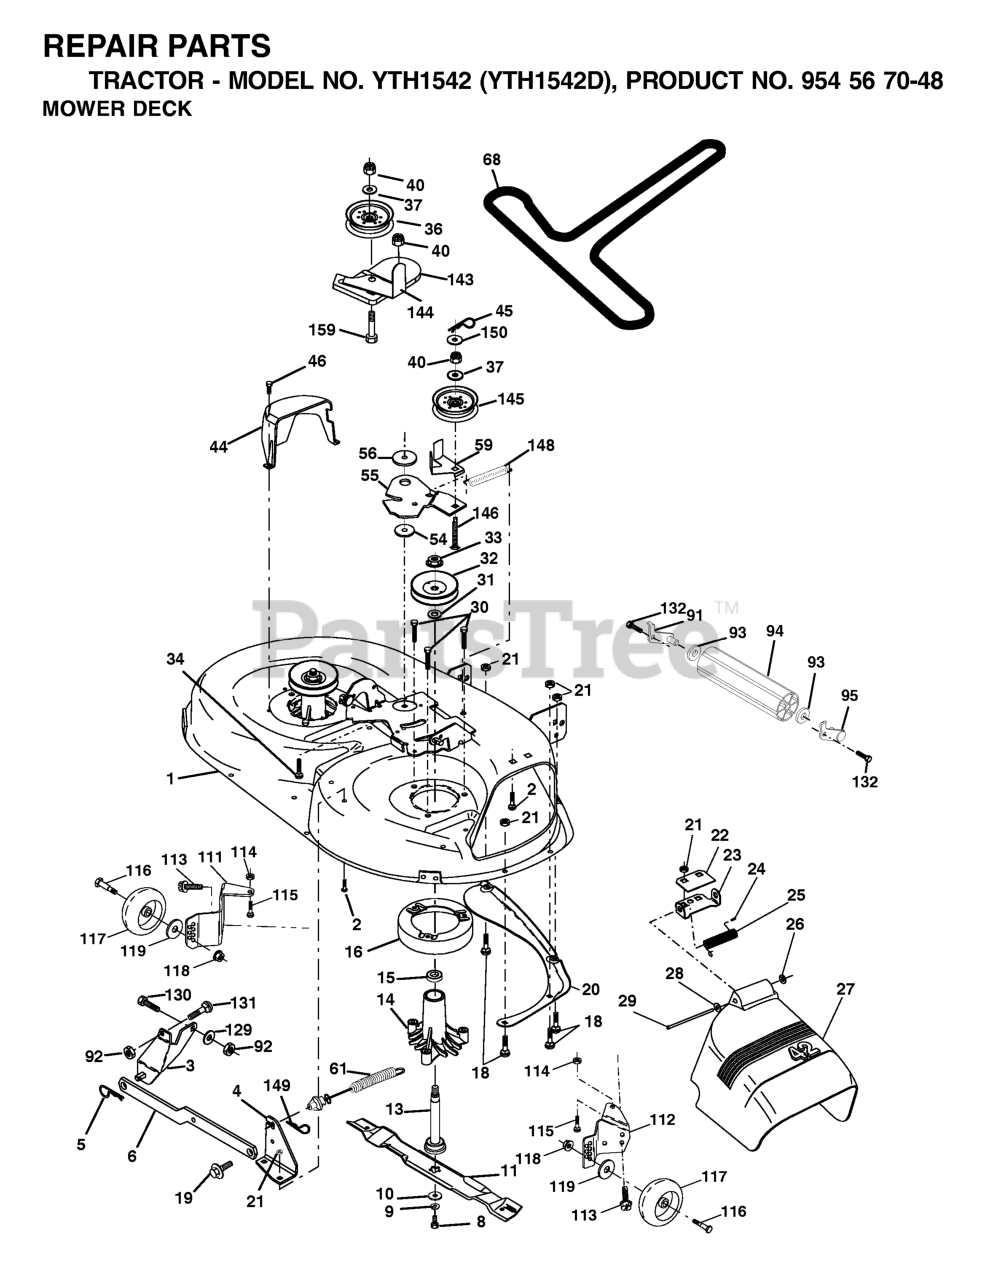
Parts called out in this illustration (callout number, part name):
1	42" DECK KIT
2	RP BOLT 5/16-18 X3/4 ZN/YEL GR
3	BRKT ASM SWAY BAR
4	BRACKET SWAY BAR 42" DECK
5	RETAINER-SPRNG RB
6	BAR SWAY DECK
8	BLADE BOLT
9	LOCKWASHER
10	WASHER.BLADE
11	Blade Mower 42" High Perf.
13	SHAFT ASM VENT
14	HOUSING.MANDREL.VENTED (MACHD)
16	STRIPPER.MANDREL.ROUND.BLACK
18	BOLT
19	BOLT SHD 5/16-18
20	BAFFLE.VORTEX
21	LOCKNUT
22	STIFFENER BRACKET
23	DEFLECTOR BRACKET
24	CAP-SLEEVE LT
25	SPRING TORSION
26	NUT PUSH M
27	SHIELD DEFLECTOR
28	Washer 11/32 x 5/8 x 16 Ga SD
29	ROD.HINGE
30	SCREW, WASHER HEAD
31	WASHER
32	PULLEY MANDREL
33	NUT, FLG TOPLOCK 9/16"
36	PULLEY.IDLER.FLAT
37	WASHER
44	GUARD MANDREL LH BLACK
45	RETAINER M
46	SCREW.1/4-20X5/8
54	HARDENED WASHER
55	ARM IDLER 42" MOWER LT/YT
56	SPACER RETAINER
59	GUARD TUV IDLER
61	SPRING EXT ELEC CLUTCH
68	V-BELT PRIMARY 42"
91	BRACKET ASM, ROLLER (L)
92	NUT
93	Washer 1 17/32 X 7/8 X 16 Ga
94	NOSE ROLLER
95	BRACKET ASM, ROLLER
111	BRACKET, WHEEL
112	BRACKET, WHEEL
113	Screw Tapping 3/8-16 x .625
114	NUT
115	BOLT.CARR.5/16-18X5/8.SHORT
116	BOLT, SHOULDER
117	WHEEL.GAUGE.STANDARD
118	LOCKNUT
119	WASHER.5/16.FLAT.STE.STD.
129	WASHER
131	BOLT D
132	SCREW 3/8-16X3/4
143	BRACKET, ARM IDLER
144	KEEPER BELT 42" CLUTCH
145	PULLEY.IDLER.FLAT.PLATED
146	BOLT, CARRIAGE IDLER BLACK
148	IDLER RETURN SPRING
149	SPRING.RETAINER.YELLOW.ZINC
